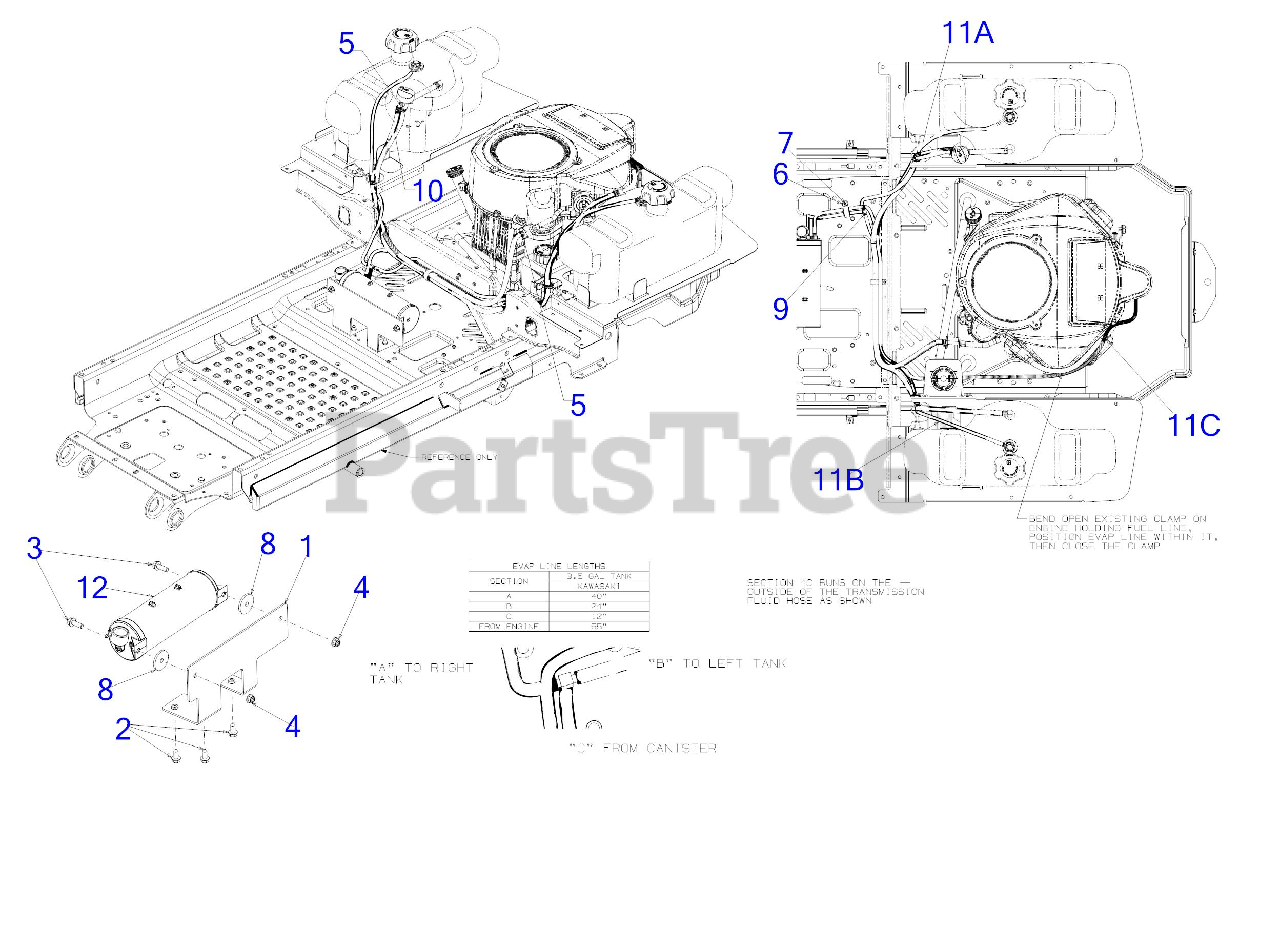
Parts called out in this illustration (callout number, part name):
1	CARBON CANISTER MOUNT BRACKET
2	SCREW 5/16-18 x .750
3	SCREW 5/16-18 x .875 GR5
4	FLANGE LOCK NUT 5/16-18
5	HOSE CLAMP 1/20
6	DRAIN HOSE CLAMP
7	RATCHET CLIP .250
8	FLAT WASHER
9	FUEL FITTING
10	FUEL HOSE LOW PERMEATION
11A	VENT HOSE 3/16 ID
11B	VENT HOSE 3/16 ID
11C	VENT HOSE 3/16 ID
12	CARBON CANISTER - 9.32 GAL
